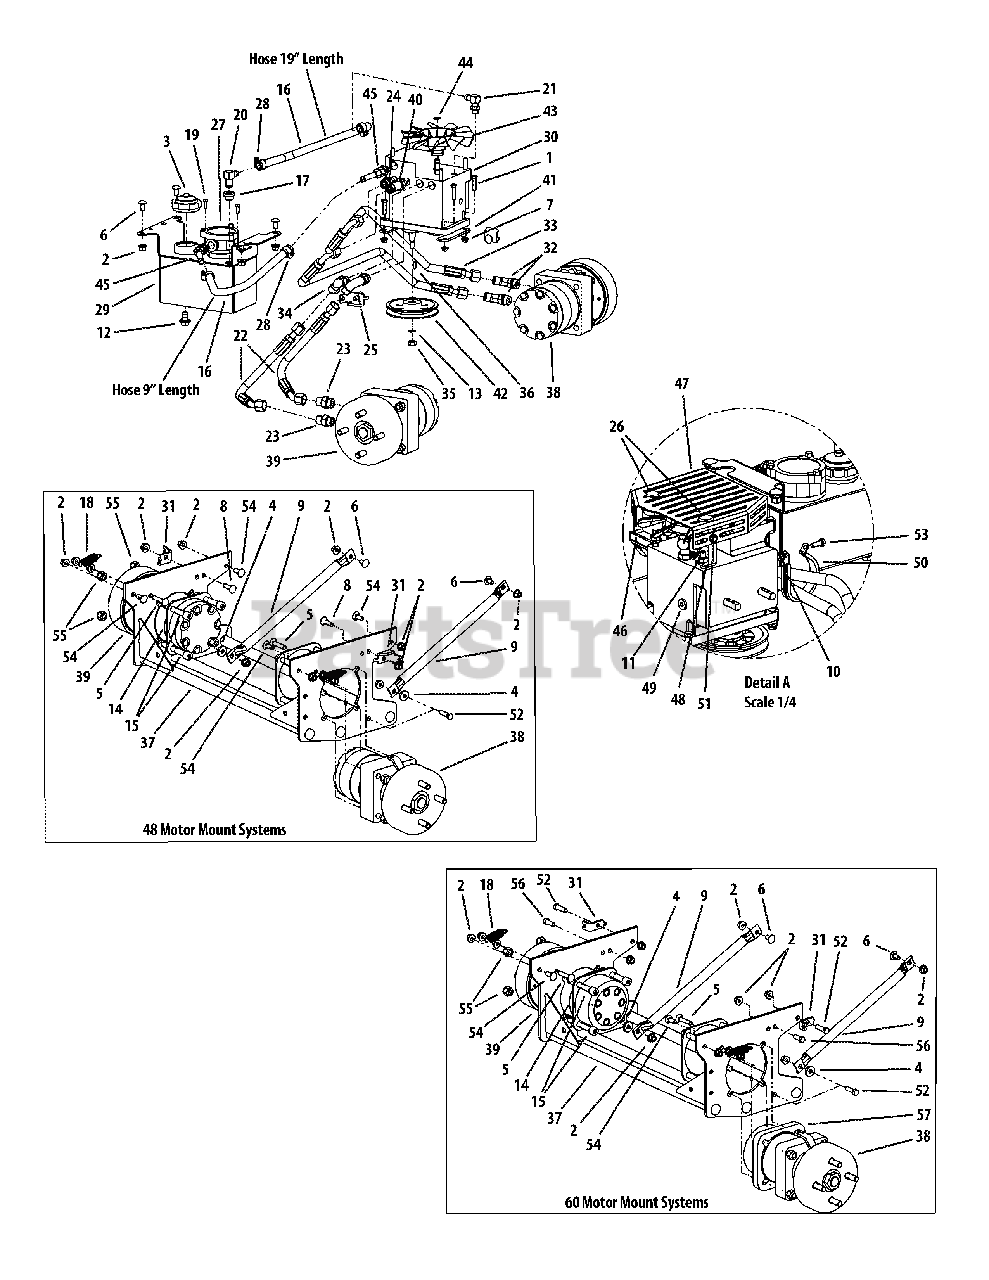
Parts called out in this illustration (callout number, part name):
1	Hex Cap Screw, 5/16-18 x 1-1/4
2	Flange Lock Hex Nut, 3/8-16
3	Cap, Hydro Oil Tank
4	Idler Washer
5	Hex Carriage Screw, 3/8-16, 1.75
6	Carriage Bolt, 3/8-16 x .75 LG.
7	Nut, 5/16-18, Flange Lock
8	Carriage Screw, 3/8-16 x 1.25
10	Nut, 1/4-20, Flange Lock
11	Hex Nut, M8 x 1.2, Nylon Top Lock
12	Oil Pan Drain Plug w/ Seal
13	Washer, 3/8 ID, External Tooth
14	Hydro Wheel Motor Backup Plate
15	Socket Head Capscrew, 1/2-13; 3-1/2
16	Hydraulic Hose, .50 ID x .75 OD
17	Grommet Fitting, .54 ID x .78 OD
18	Spring Extension, .740 OD x 2.656
19	Socket Head Cap Screw, 1/4-20 x 0.75
20	Fitting Elbow Spur, 5/8 x 1/2
21	Fitting Elbow, 9/16 x 1/2
22	Short Pressure Hose Assembly
23	Adaptor Fitting, 8 x 10
24	Adaptor Fitting, 8 x 8
25	Adaptor, 8 x 8
26	Plastic Plug
27	Hydraulic In-Tank Filter includes:
27	Replacement Filter
28	Hose Clamp, 1/2
29	Hydraulic Tank Assembly
30	Hydro Pump
31	Rear Cable Mounting Bracket (48")
31	Rear Cable Mounting Bracket (60")
32	Adaptor Fitting, 8 x 10
33	Long Pressure Hose Assembly
34	Adaptor Fitting, 8 x 8
35	Nut, M10 x 1.5, Left Hand
37	Hydro Motor Frame Assembly
38	Hydro Motor, RH Assembly (48")
38	Hydro Motor, RH Assembly (60")
39	Hydro Motor, LH Assembly (48")
39	Hydro Motor, LH Assembly (60")
40	Adaptor Fitting, 8 x 8
41	Spacer Plate, Pump
42	Hydro Pump Pulley
44	E-Clip
45	Fitting, 3/4 ORB x 1/2 Tube
46	Left Hand Fan Bracket
48	Right Hand Fan Bracket
49	Plug Adaptor
50	Clamp, 2.00 x 3.50
51	Self Tapping Screw, 1/4-20 x 0.375
52	Hex Cap Screw, 3/8 -16 x 1.25
53	Hex Cap Screw, 1/4-20 x 0.75
54	Carriage Bolt, 3/8-16 x 1
55	Washer lock 3/8 zinc
56	Hex Cap Screw, 3/8-16 x 1.00 (60")
57	Spacer, Hydro Wheel Motor (60")
